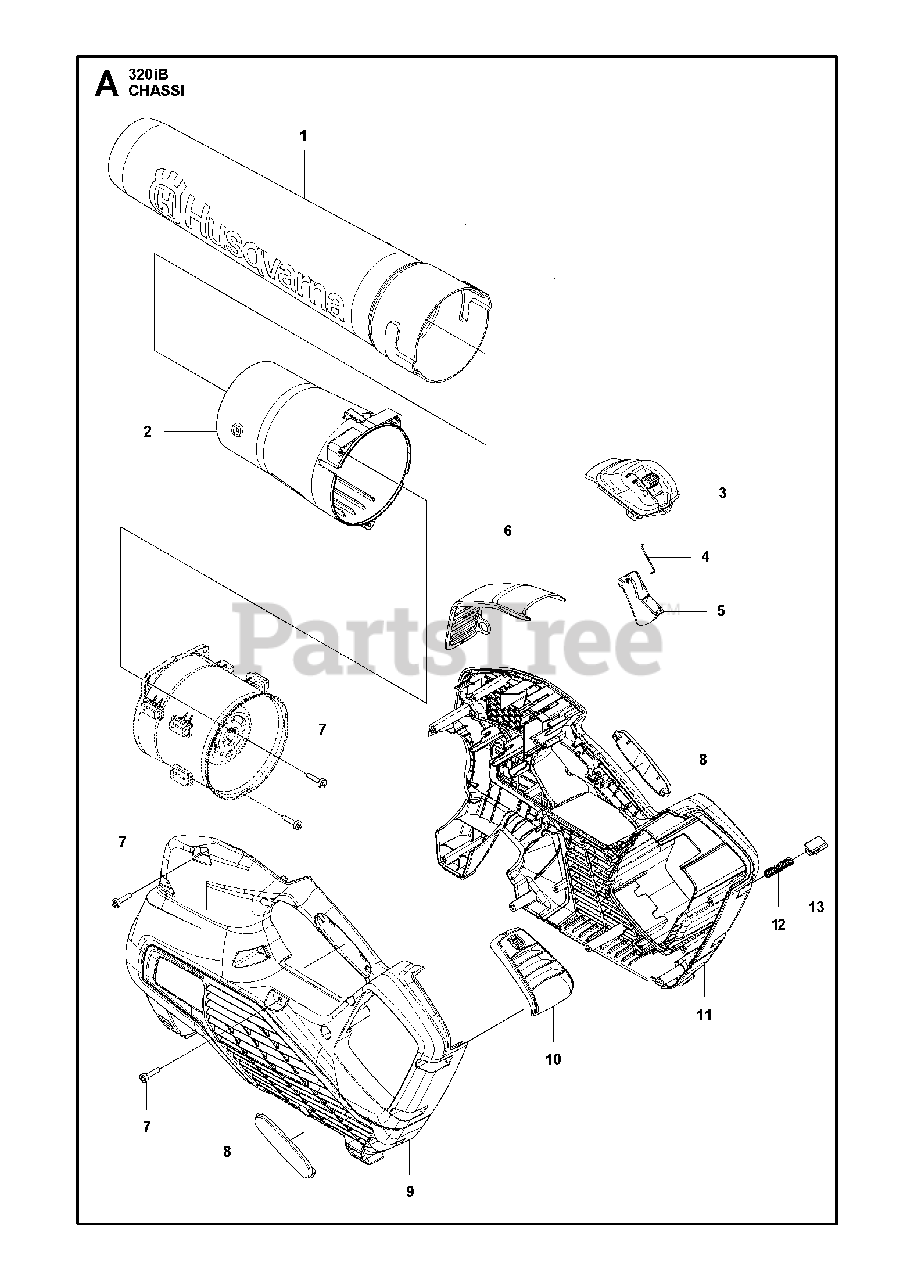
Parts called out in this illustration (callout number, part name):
1	NOZZLE BLOWER 320IB
2	TUBE FAN SYSTEM
3	CONTROL MECHANICAL CRUISE
4	PULL ROD MEC CRUISE 27MM
5	THROTTLE CONTROL MECHANICAL CR
7	SCREW
8	HANDLE INSERT GREY
9	HOUSING LEFT
11	HOUSING RIGHT
12	SPRING PUSH OUT
13	PUSH BUTTON
